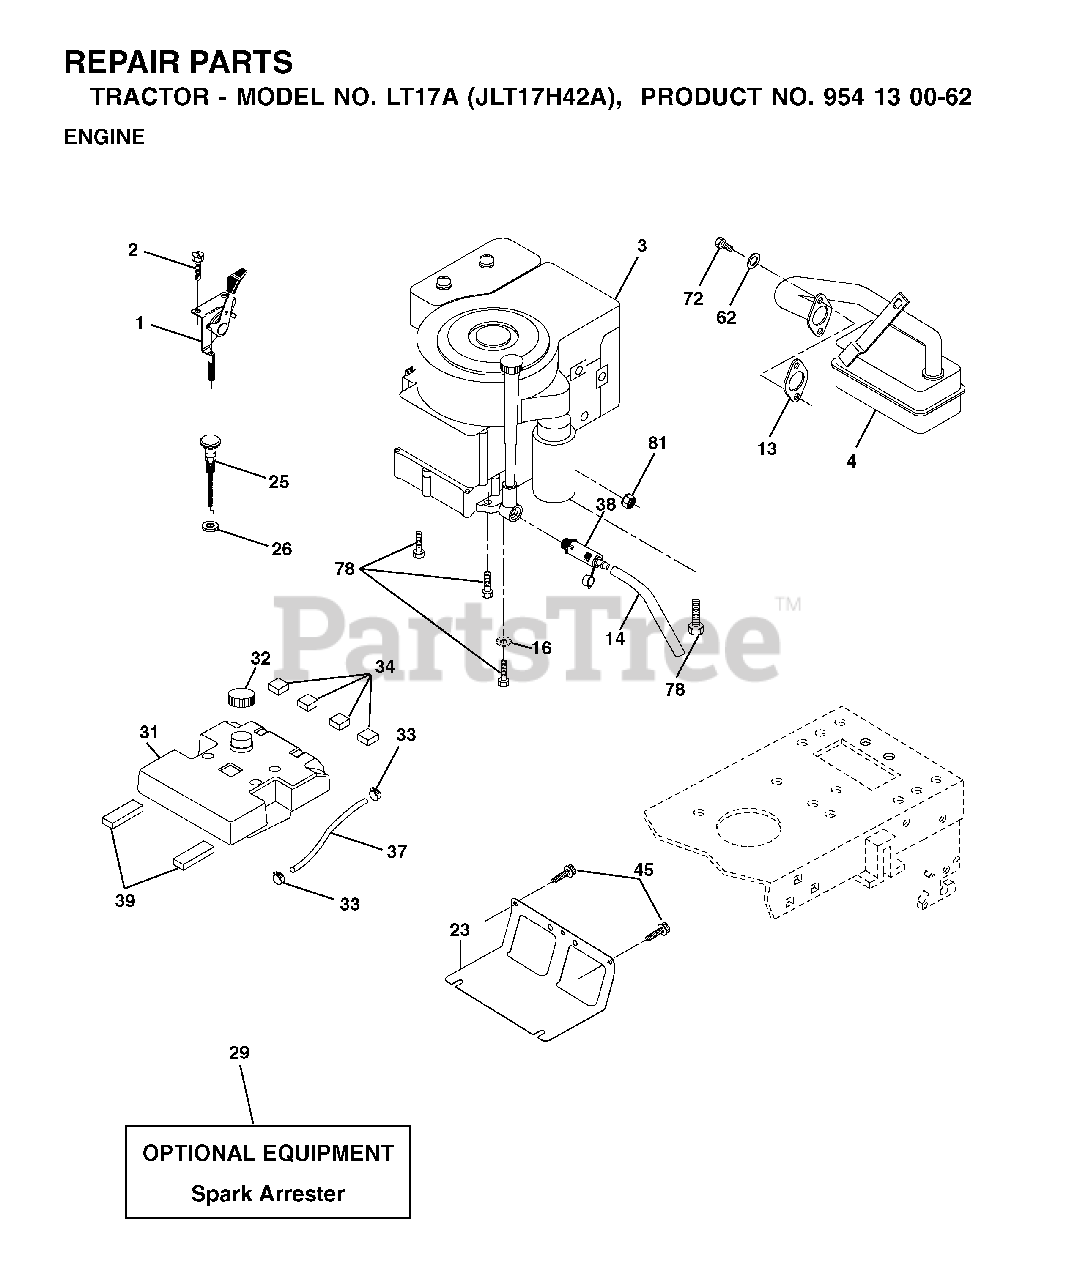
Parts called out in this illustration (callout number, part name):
1	CONTROL.TH/CK.C.
2	SCREW
13	REPL BY 532 27 22-93
14	TUBE, DRAIN OIL ASM.
16	LOCKWASHER
23	SHEILD.BROWNING.DBR.GUARD
26	NUT KEPS 3/8 - 24 UNF
29	ARRESTER SPARK (OPTIONAL)
31	TANK.FUEL(3.5.GAL)
32	FUEL CAP
33	HOSE CLAMP
34	PAD-SPACER LT
38	PLUG, OIL DRAIN EASY
39	PAD IDLER TI
45	SCREW, 3/8-16X3/4
62	LOCKWASHER
72	SCREW
78	SCREW.3/8-16
81	NUT
